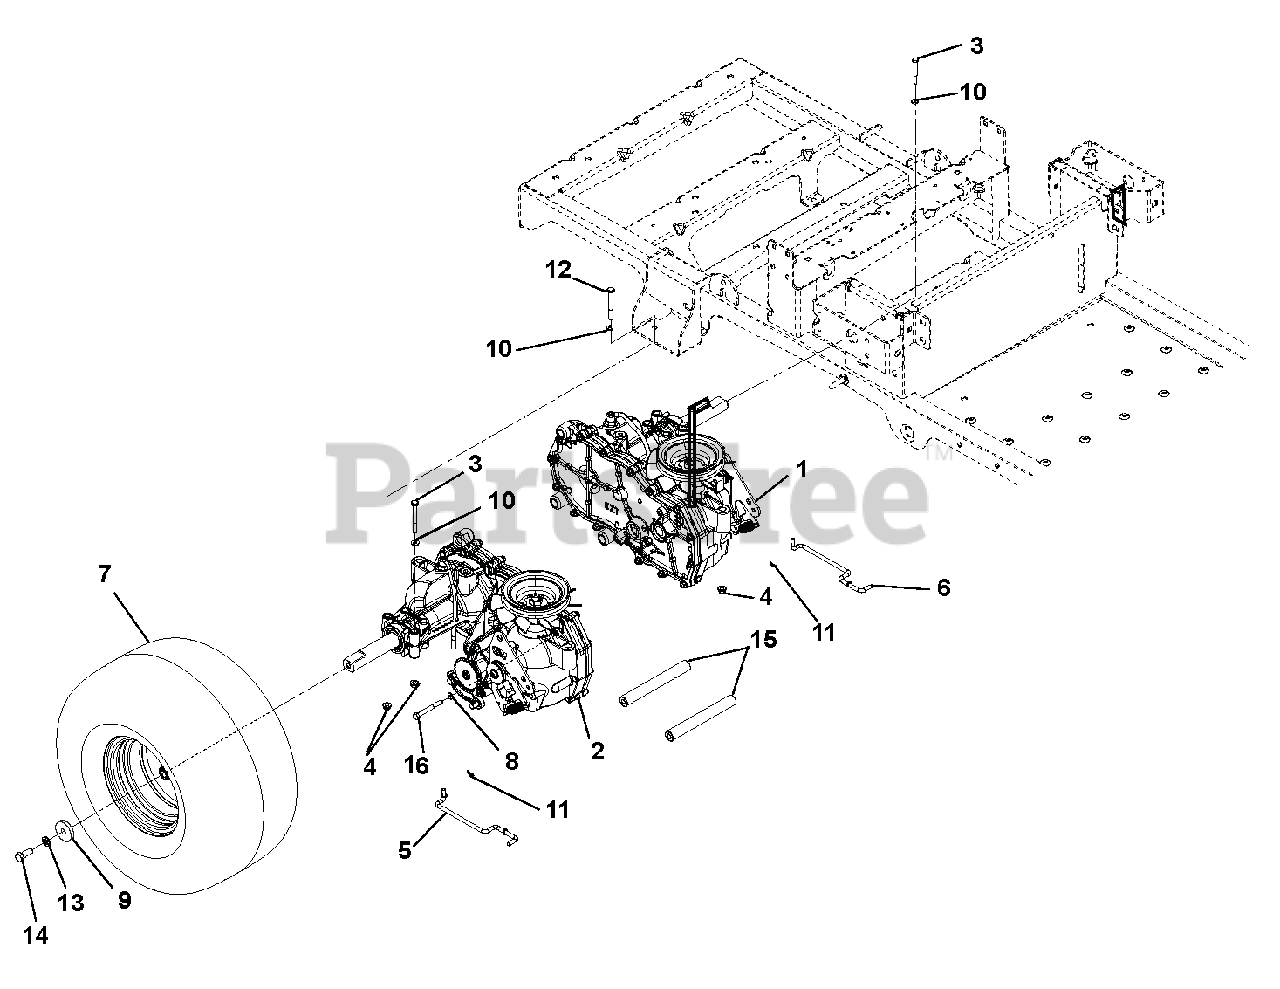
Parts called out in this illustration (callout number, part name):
1	TRANSAXLE, LH EZT D-SHAFT
1	TRANSAXLE, LH EZT D-SHAFT LONG
2	TRANSAXLE, RH EZT D-SHAFT
2	TRANSAXLE, RH EZT D-SHAFT LONG
3	@BLT-HEX .31-18X2.25 GR5 YWZC
4	@NUT-LK-NYL-FLG .31-18 YWZC
5	DUMPVALVE, RH LCZ
6	DUMPVALVE, LH LCZ
7	TIRE-ASM 18X6.5-8 4 PLY DSHAFT
7	TIRE/WHEEL ASSY,18X8.50-8 DHUB
7	TIRE/WHEEL ASSY,18X9.50-8 DHUB
8	WSHR-FL-STL .406X1.00X.188 YWZ
9	WSHR,FLT STL.406X1.50X.245YWZC
10	@WSHR-FL-STL.38X.875X.083 YWZC
11	PIN-HAIR INT .06X.18X.77
12	@BLT-HEX .31-18X2.75 GR5 YWZC
13	@WSHR-LK .38X.094 REG YWZC
14	BLT-HEX .38-16X1.0 GR8 YZ EP30
15	SHAFT, TRANSAXLE BRACE
16	@BLT-HEX .38-16X2.50 GR5 YWZC
